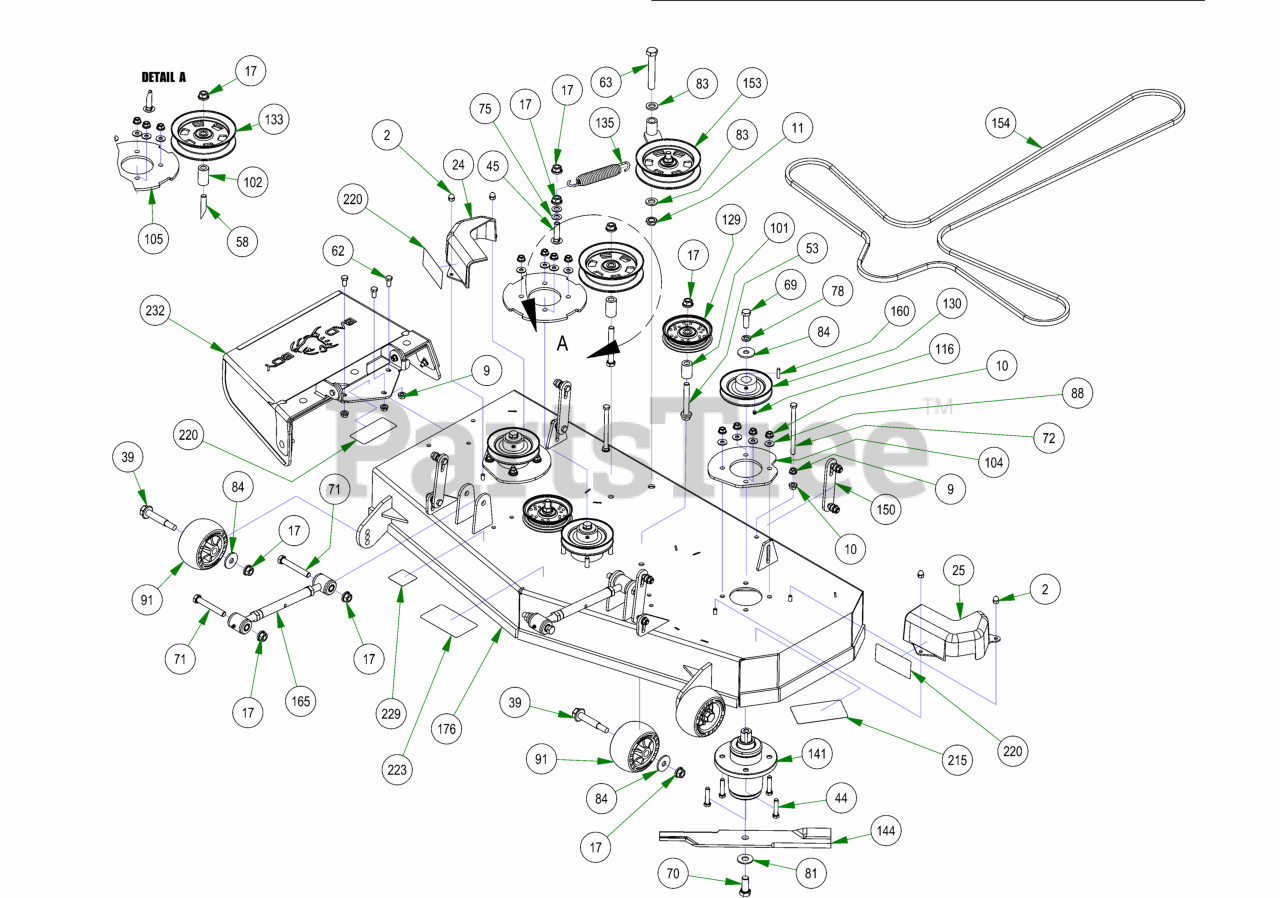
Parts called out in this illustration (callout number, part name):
2	5/16-18 ACORN NUT HIGH-CROWN ZC
9	3/8-16 HEX SERRATED FLANGE NUT HARD/ZINC
10	3/8-16 NYLON INSERT FLANGE LOCKNUT (GR.F) ZINC
11	5/8-11 NYLON INSERT JAM LOCKNUT ZINC
17	1/2-13 NYLON INSERT FLANGE LOCKNUT ZINC
24	pulley cover chute side
25	pulley cover non-chute side
39	Deck Wheel Bolt
44	3/8-16 X 1-3/4 HEX C/S (GR.5) ZC
45	1/2-13 X 2 CARRIAGE BOLT ZINC
53	1/2-13 X 3-1/2 HEX FLANGE BOLT (GR.8) ZINC
58	1/2-13 X 4 HEX CAP SCREW (GR.8) ZINC YELLOW
62	3/8-16 X 3/4 HEX CAP SCREW (GR.5) ZINC
63	5/8-11 X 4 HEX CAP SCREW (GR.8) ZINC YELLOW
69	1/2-20 X 1-1/2 HEX CAP SCREW (GR.5) ZINC
70	5/8-18 X 1-1/2 HEX CAP SCREW (GR.8) ZINC YELLOW
71	1/2-13 X 3-1/2 HEX CAP SCREW (GR.5) ZINC
72	3/8-16 X 5-1/2 HEX CAP SCREW (GR.5) ZINC
75	.517 SQ WDTH ID X .937 OD X .060 THICK F/W PHOS/OIL
78	1/2 SPLIT LOCKWASHER (GR.8) ZINC/YELLOW
81	5/8 USS FLAT WASHER (1-3/4" OD) GR.8 ZINC YELLOW
83	.635 ID X 1.120 OD X .140 THICK FLAT WASHER NYLON
84	1/2 BELLEVILLE WASHER (1-5/8 OD X .140 THK) ZINC
88	5/16 USS FLAT WASHER (7/8 OD) ZINC
91	Deck Wheel
101	.502 ID X .750 OD X 1.500 Long Spacer
102	1 3/4" Pulley Spacer
104	42&48 Deck Spindle Support Plate
105	Deck Spindle Support Plate
116	5/16-24 X 1/4 SOCKET SET SCREW (CUP PT) PLAIN
129	4 3/4 Idler Pulley - ABFI-76
130	5" Spindle Deck Pulley
133	5-3/4 Idler Pulley
135	Deck Idler Spring
141	OUTLAW SPINDLE ASSEMBLY
144	48" ZT/Mav/Compact Outlaw Blade with Fusion
150	Deck Hanger Assembly
153	2017 54"/48" Deck Idler Assembly
154	B147 Deck Belt
160	1/4 X 1 SQ MACHINERY KEY 1018 STL PLN
165	2018 Maverick Turnbuckle (Top Link)
176	2017 48" ZT Deck Welded Assembly
215	2018 48" Deck Decal
220	Danger Decal-Spindle/Discharge
223	Deck Belt Route Decal
229	Deck Impact Patent Decal 9591803
232	ZT Chute Assembly
